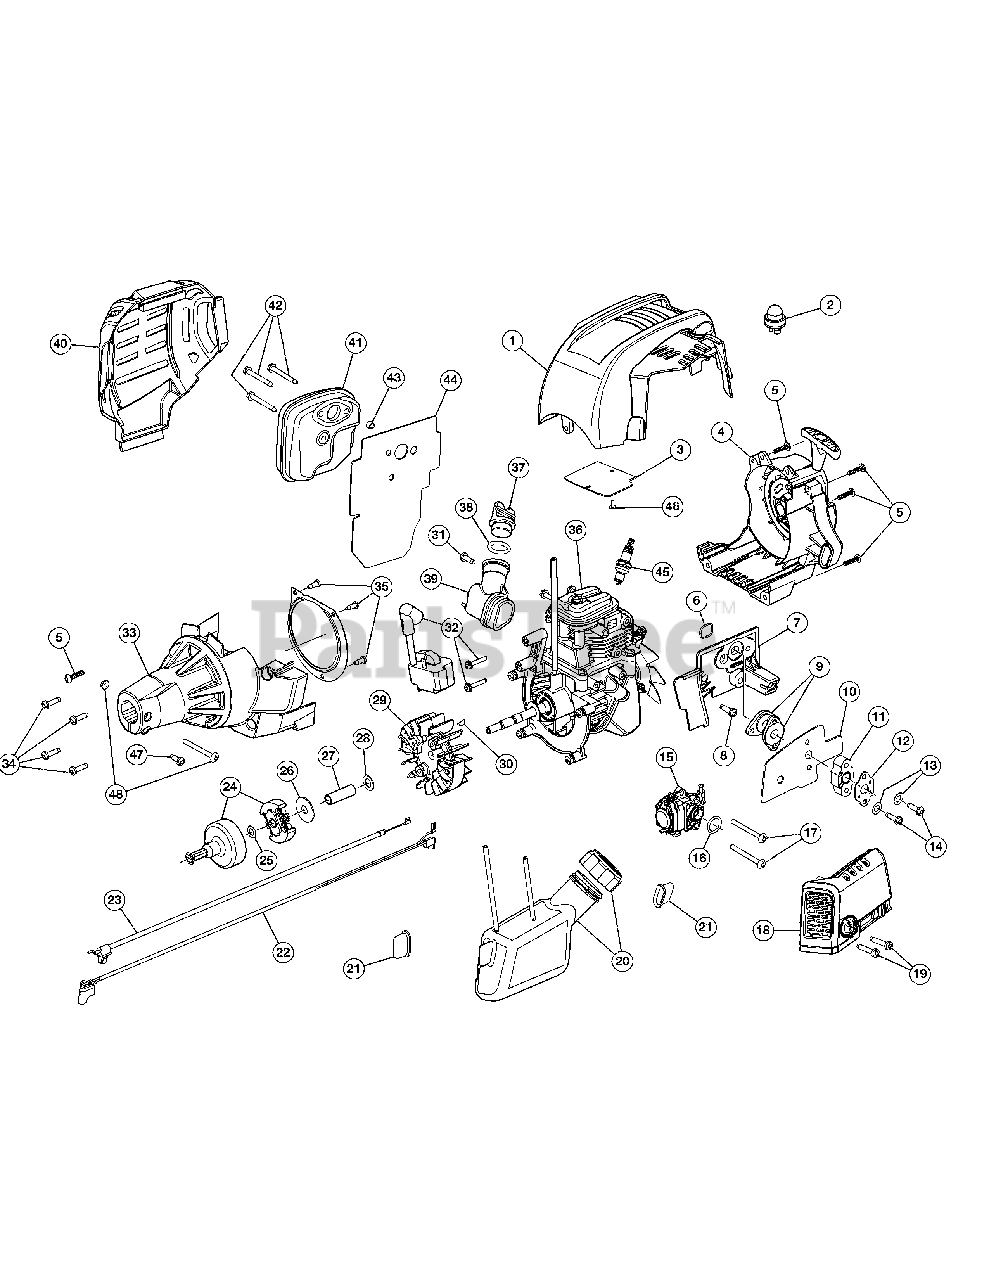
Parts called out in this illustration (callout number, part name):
1	Top Housing Assembly (Incl. 3 & 46)
2	Air Purge Primer
3	Top Cover Gasket
4	Starter Housing Assembly (Incl. 5)
7	Intake Port
8	Screw
9	Boot Assembly
10	Carburetor Gasket
11	Insulator
12	Insulator Gasket
14	Screw
15	Carburetor Assembly (Incl. 16)
18	Air Cleaner Assembly (Incl. 19)
20	Fuel Tank Assembly
21	Fuel Tank Pad
22	Lead Wire
23	Throttle Cable
24	Clutch Assembly (Incl. 25 & 26)
25	Thrust Washer
26	Clutch Washer
27	Power Shaft Spacer
28	Washer
29	Flywheel Assembly (Incl. 30)
32	Module Assembly
33	Clutch Cover Assembly (Incl. 35)
36	Short Block Assembly
37	Oil Fill Plug
39	Oil Fill Tube Assembly (Incl. 37 & 38)
40	Muffler Housing
41	Muffler Assembly (Incl. 42 - 44)
42	Screw
43	Air Cleaner Spacer
44	Muffler Gasket
45	Spark Plug
47	Anti-Rotation Screw
48	Clamp Hardware
